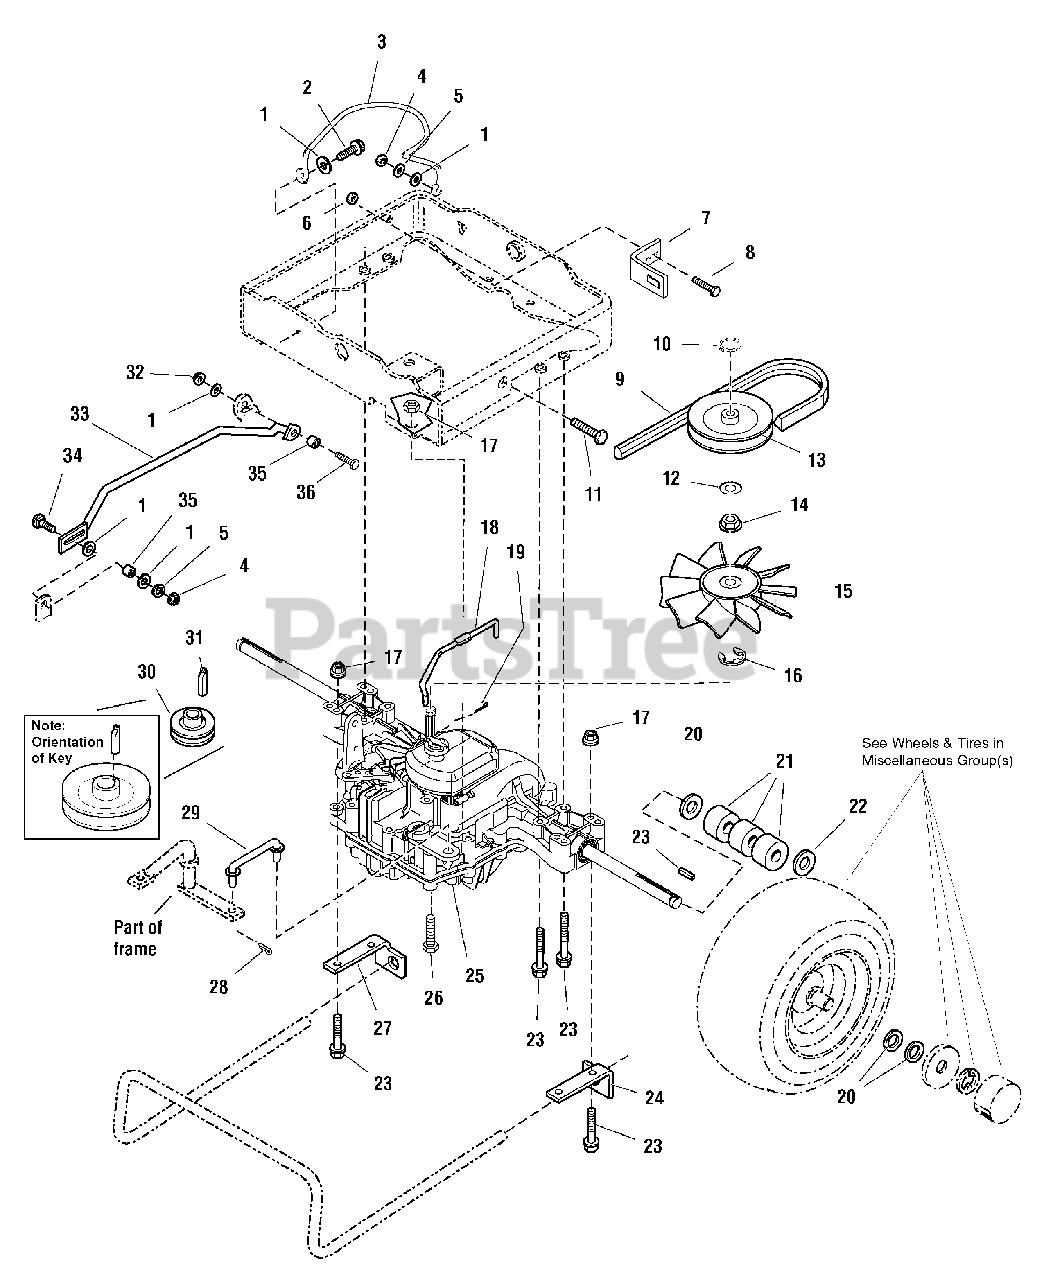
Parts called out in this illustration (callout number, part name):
2	SCREW, Hex Washer Head Taptite, 5/16-18 x 3/4
4	NUT, Hex 5/16-18
5	LOCKWASHER, 5/16
6	NUT, Flange, Nylon 1/4-20
7	BRACKET, Switch
8	CARRIAGE BOLT, 1/4-20 X 5/8
10	SNAP RING
11	CAPSCREW, Hex Head, 5/16-18 x 1
12	LOCKWASHER
13	PULLEY
14	SPLINE COLLAR
15	FAN
16	E RING
17	NUT, Hex Flange Whizlock, 5/16-18
19	PIN, Cotter
22	KEY
23	CAPSCREW, Hex Head Taptite, 5/16-18 x 2-1/2
24	ANCHOR, Torsion Bar LH
25	TRANSMISSION ASSEMBLY
26	CAPSCREW, Hex Head Flange Whizlock, 5/16-18 x 1-3/4
27	ANCHOR, Torsion Bar RH
28	PIN, Cotter
30	PULLEY & HUB ASSEMBLY
32	NUT, Hex Two Way Lock, 5/16-18
33	CONTROL, Rod
34	CARRIAGE BOLT, 5/16-18 x 1
36	CAPSCREW, Hex Head, 5/16-18 x 1-1/4
